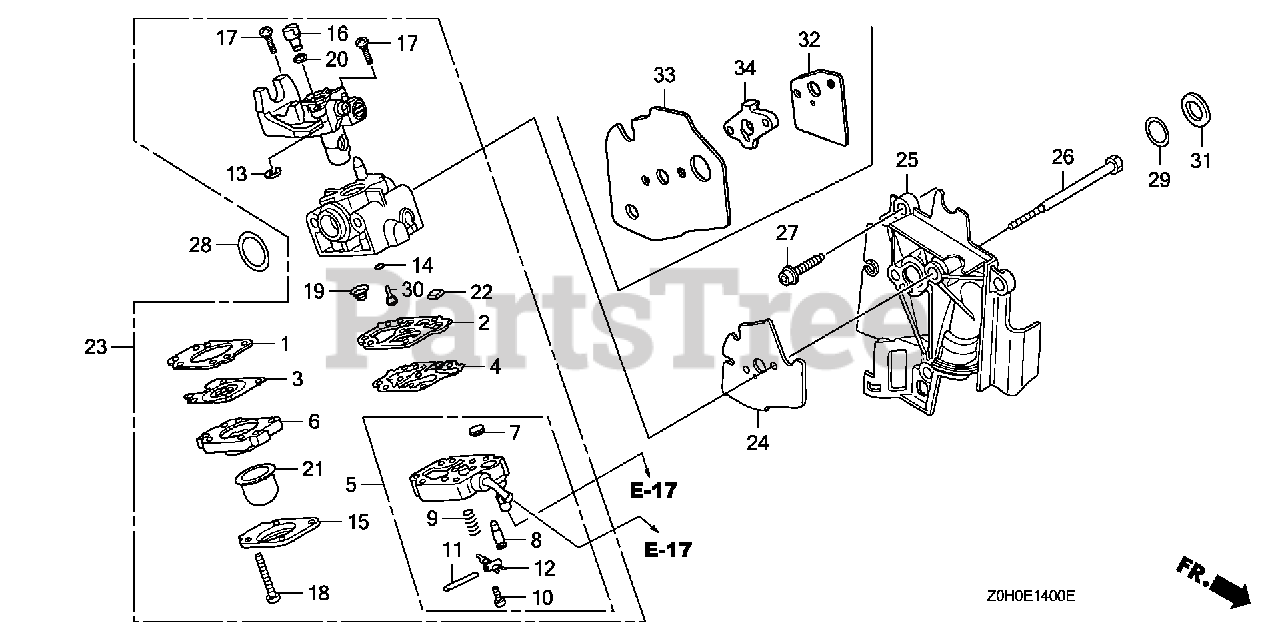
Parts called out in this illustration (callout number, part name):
1	GASKET, METERING DIAPHRAGM
2	GASKET, PUMP (CARBURETOR NO.)
3	DIAPHRAGM ASSY., METERING
4	DIAPHRAGM, PUMP
5	BODY ASSY., PUMP (CARBURETOR NO.)
6	BODY ASSY., AIR PURGE
7	SCREEN, INLET
8	VALVE, INLET NEEDLE
9	SPRING, METERING LEVER
10	SCREW, METERING LEVER PIN
11	PIN, METERING LEVER
12	LEVER, METERING
13	RING, RETAINING
15	COVER, PRIMER PUMP
17	SCREW, THROTTLE COLLAR
18	SCREW, PUMP COVER
19	SPRING, PUMP
21	PUMP, PRIMER
22	FILTER, FUEL INLET
23	CARBURETOR ASSY. (WYB 9B)
24	GASKET, CARBURETOR
26	BOLT (5X53)
27	BOLT, SOCKET (5X16)
28	O-RING (14.8X2.4)
29	O-RING (12.3X2.4)
30	JET (#33) (CARBURETOR NO.)
30	JET (#34) (CARBURETOR NO.)
30	JET (#32) (CARBURETOR NO.)
